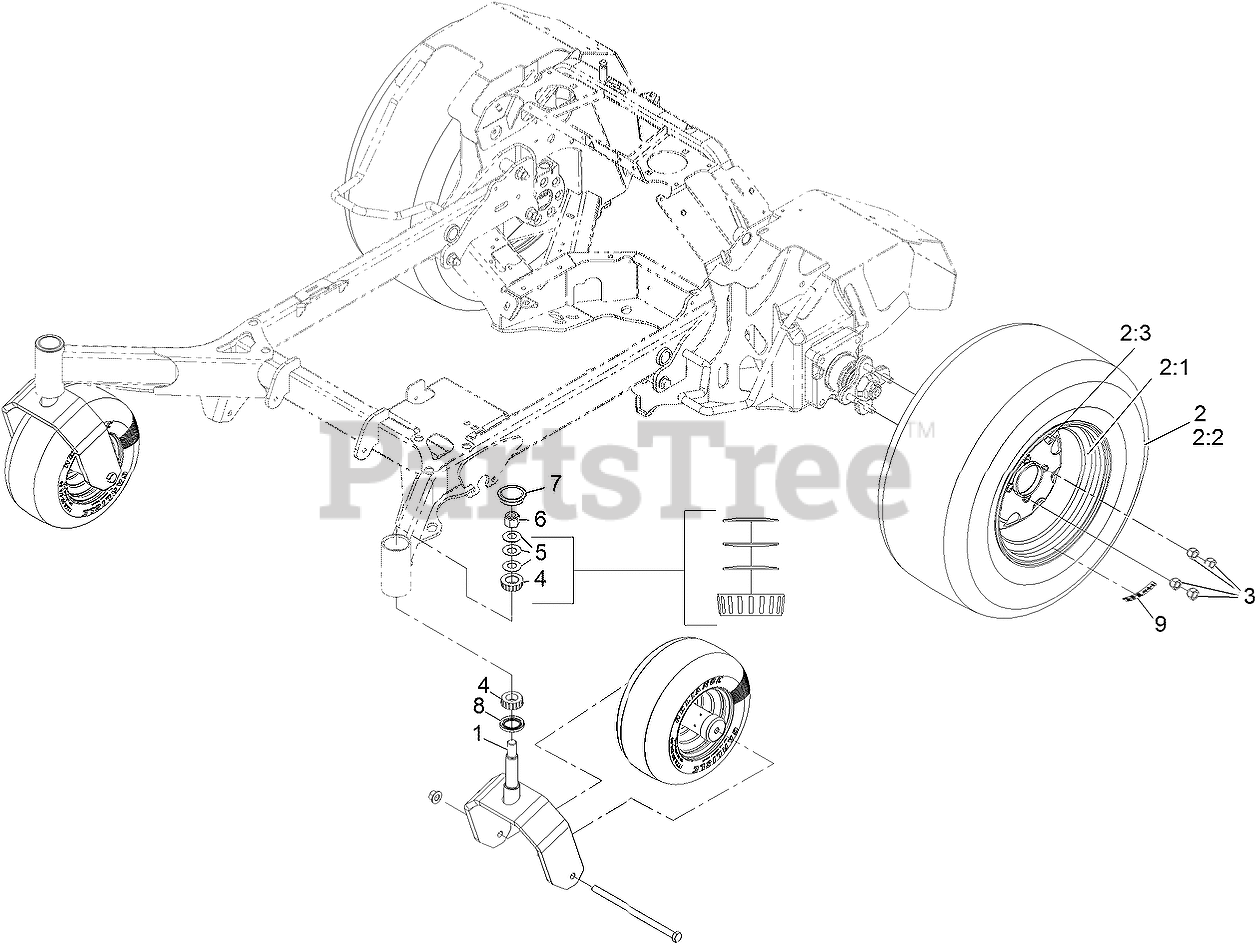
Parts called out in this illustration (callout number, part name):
2	ASM, Wheel And Tire
2:1	Rim, 12 X 8.5
2:2	Tire, 23 X 10.50-12
2:3	Stem-Valve
3	NUT-LUG
4	Cone-Bearing Tapered Roller
5	WASHER-BELLVILLE
6	NUT-LOCK, NI
7	CAP-GREASE
8	SEAL-GREASE
9	DECAL-TORQUE, WHEEL HUB LUG
